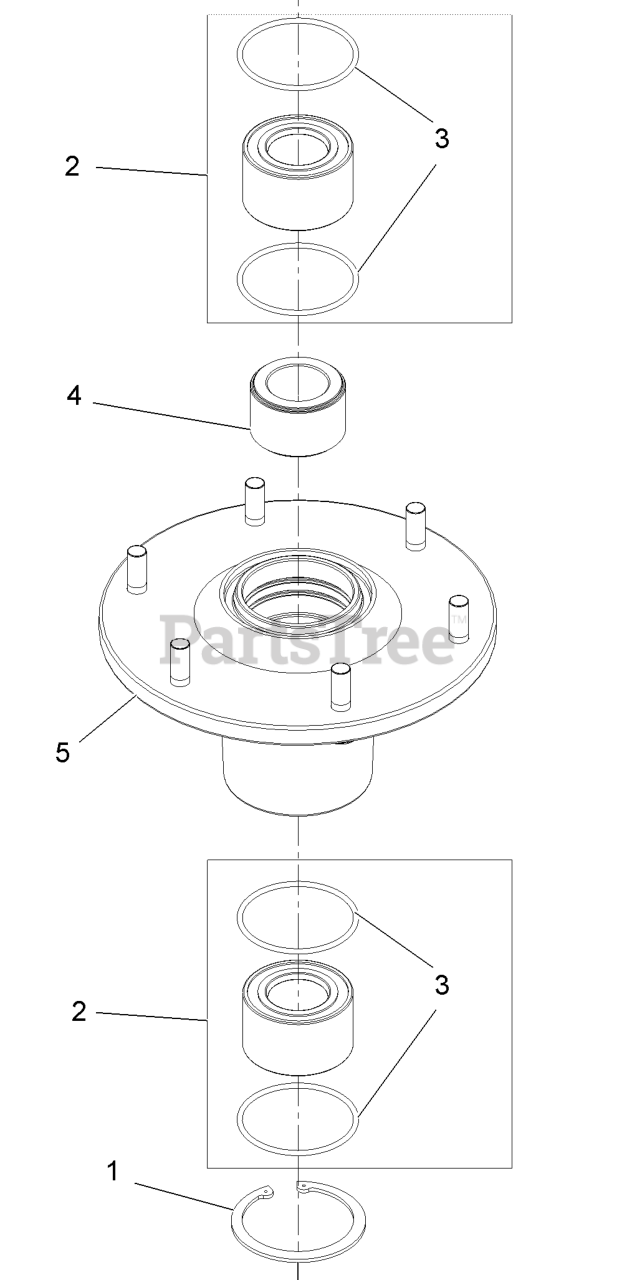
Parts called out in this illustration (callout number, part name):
1	Ring-Retaining
2	Asm, Bearing W/O-Rings
4	Spacer, Bearing
5	Asm, Housing W/Studs
